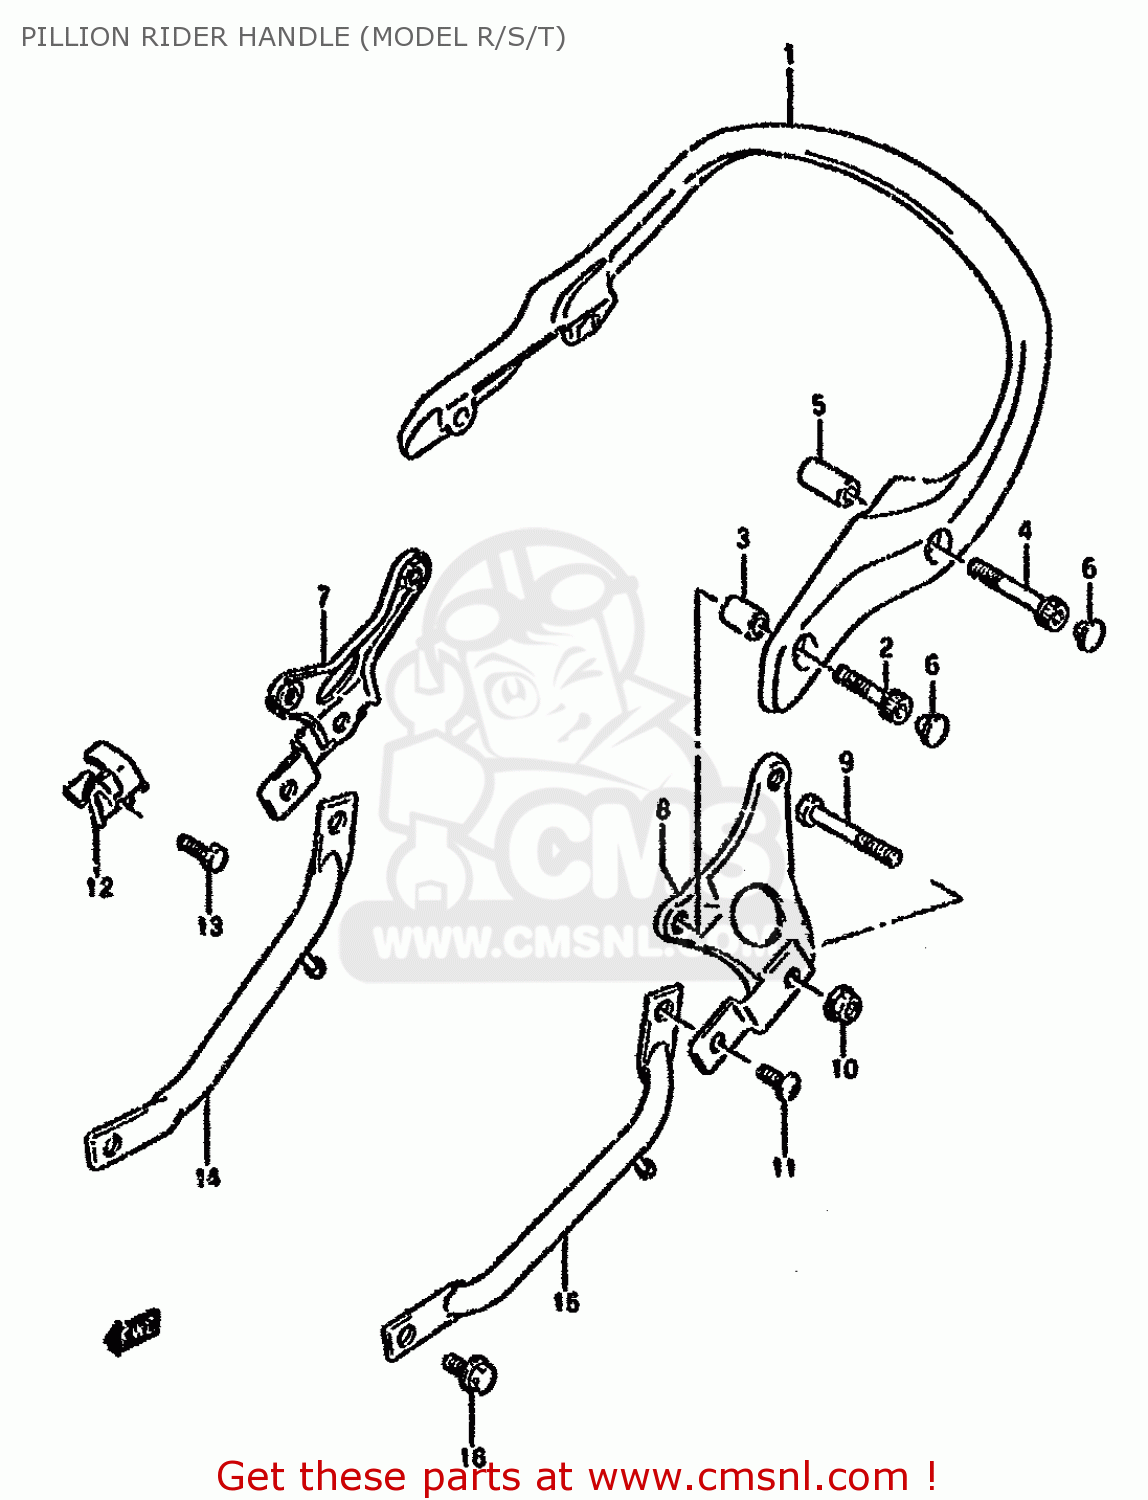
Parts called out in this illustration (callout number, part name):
1	HANDLE,PILLION RIDER
2	BOLT
3	SPACER (8.6X13.8X21.5)
4	BOLT
5	SPACER (8.6X13.8X28)
6	CAP(OD:14.5)
7	BRACKET,PILLION RIDER HANDLE,R
8	BRACKET,PILLION RIDER HANDLE,L
9	BOLT
10	NUT
11	NUT
12	SCREW
13	BOLT
14	BOLT
15	GRIP,RR,L
16	GRIP,REAR,RIGHT
17	GRIP,REAR
18	BOLT, LOWER
